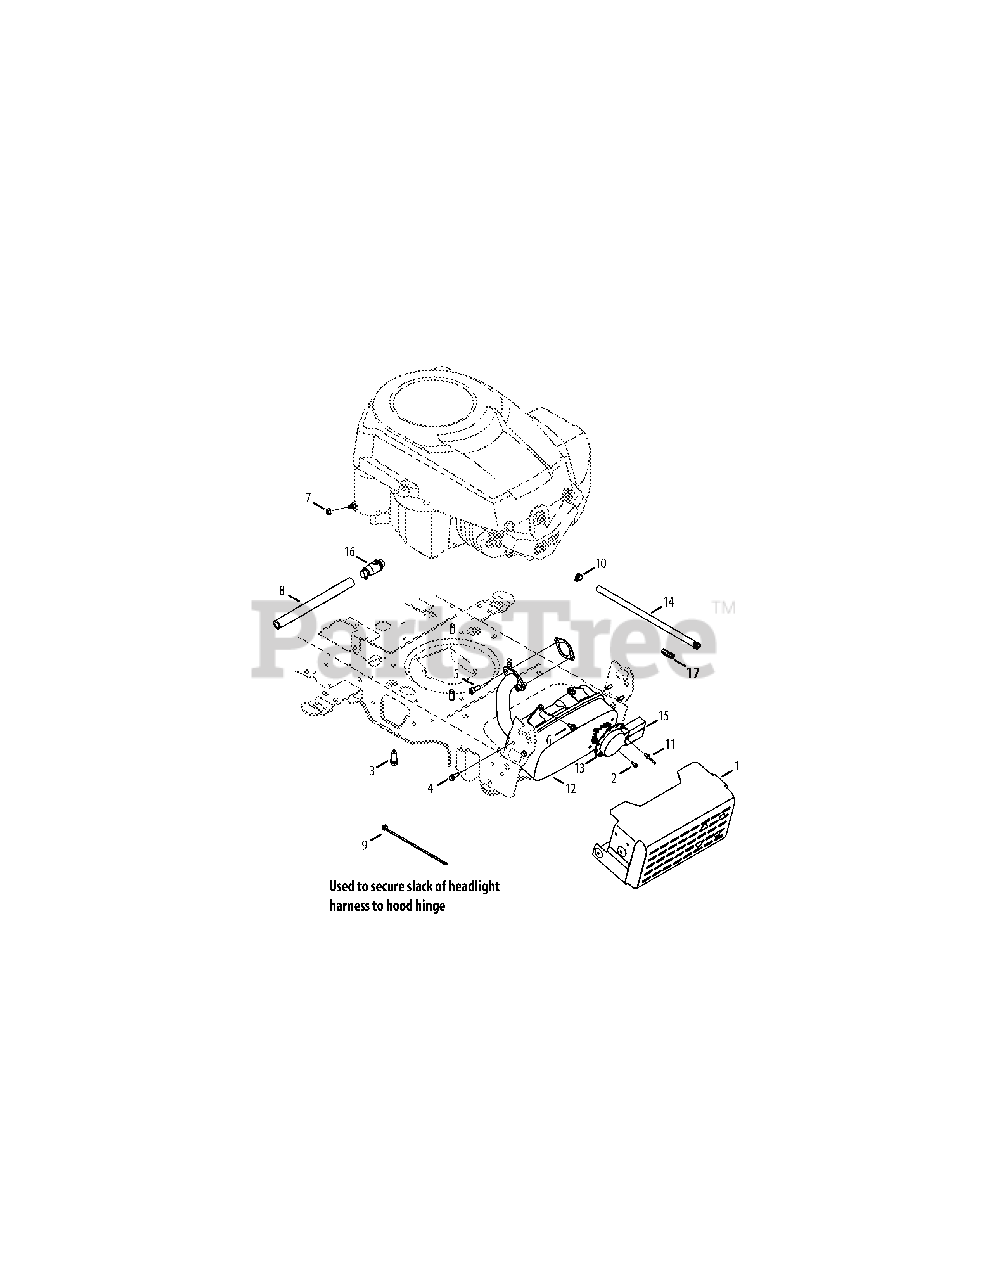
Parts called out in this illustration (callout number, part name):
1	Muffler Shield Assembly
2	Screw, Indented Washer, #8-18:0.500
3	Taptite Screw, 3/8-16:1.000
4	Taptite Screw, 1/4-20:0.500
5	Socket Head Screw, 5/16-18:.750
6	Taptite Screw, 1/4-20 x .625
7	Sems Nut, 1/4-20
8	Extension Hose, Oil Drain
9	Cable Tie, 3/16 x .05 x 7.4
10	Hose Clamp, .490 DIA.
11	Rivet, .188 DIA x .300 L
12	Muffler, EPA
13	Muffler Deflector
14	Fuel Hose
15	Long Muffler Deflector, EPA
16	Oil Drain
17	Hose, Vent
